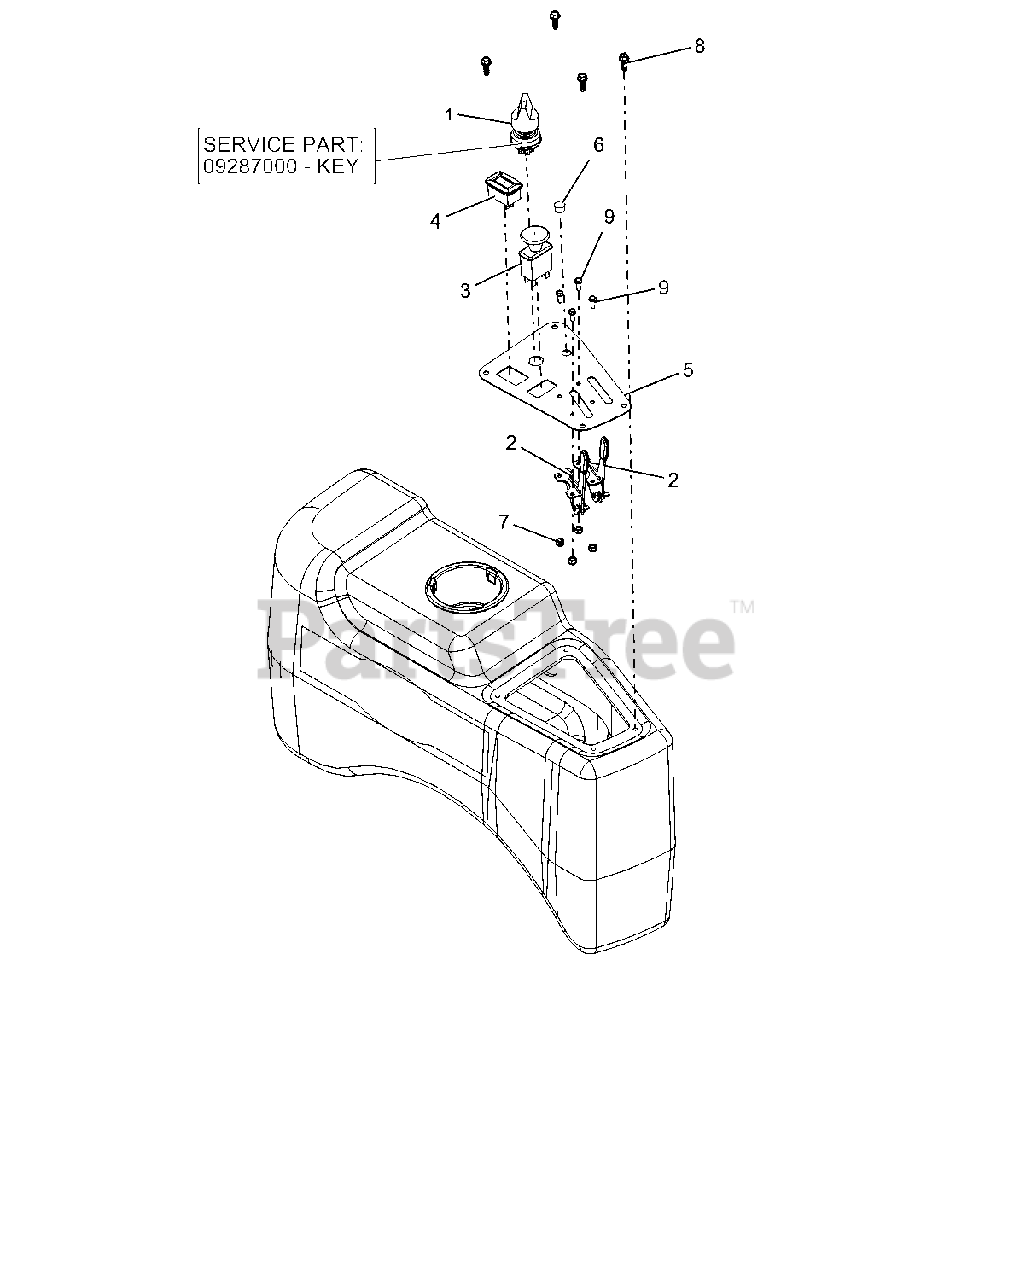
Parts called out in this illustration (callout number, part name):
1	KEY, W/ SHIELD
1	SWITCH, IGNITION
2	CABLE, CONTROL
3	SWITCH, CLUTCH
4	METER, HOUR W/MAINTENANCE
5	INSTRUMENT PANEL - BLK
6	PLUG-HOLE .50 DIA
7	@NUT-LK-NYL 10-24 W/INSRT YWZC
8	SCR-PLASTITE .25-10X.75, YWZC
9	@SCR-MCH 10-24X.50 HWH YWZC
